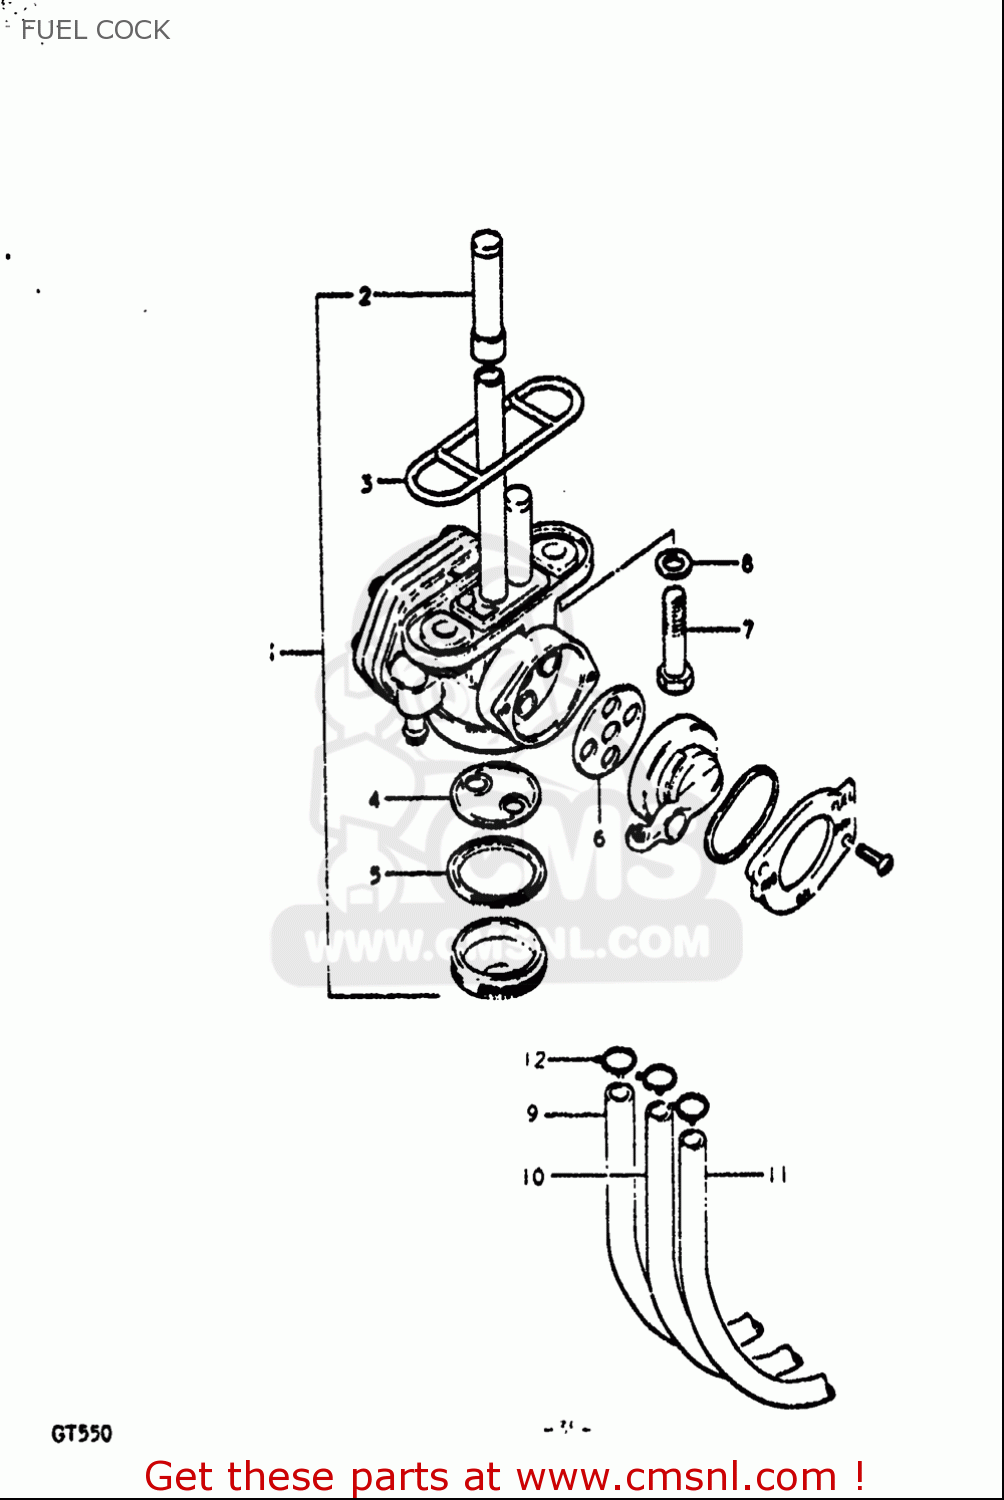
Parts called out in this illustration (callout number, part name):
1	COCK ASSY,FUEL
2	FILTER
3	GASKET, FUEL COCK (NAS)
4	FILTER,CUP
5	GASKET,CUP (NAS)
6	GASKET,FUEL COCK LEVER (NAS)
7	BOLT
8	GASKET(5.8X13X1.2) (NAS)
9	HOSE(5X8.2X2000)
10	HOSE(5X9X600)
11	HOSE(5X8.2X600)
